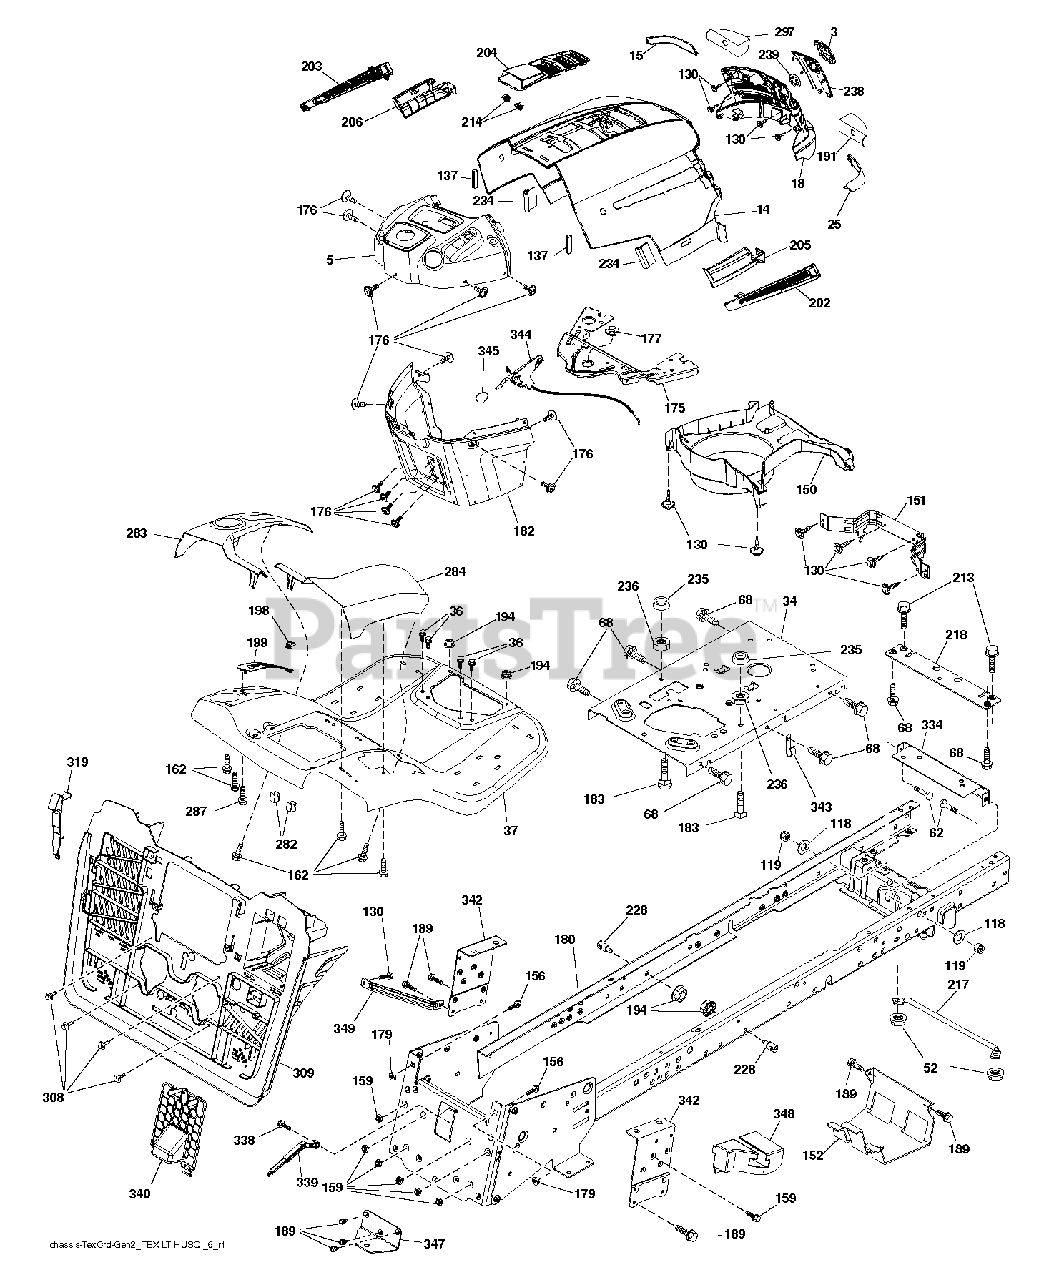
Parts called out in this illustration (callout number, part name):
3	LOGO.HUSQ.GT.LT.CROWN.H
5	SUBASM.DASH.UPPER.HLT.498
14	HOOD.HUSQVARNA.LT.ORANGE
15	LENS.HUSQVARNA LT.RH
18	GRILLE.SVC.HUSQVARNA.GREY
25	LENS.HUSQVARNA LT.RH
34	PLATE.ENGINE.10GA.CRD.GENII
36	SCREW 5/16"
37	FENDER.TEX.SRD.CRD.BASE
52	LOCKNUT
62	BOLT D
68	SCREW LT
118	WASHER
130	SCREW.#10 X 0.750.BOS
137	BUMPER DASH
151	BRACKET PIVOT
152	SHIELD.BROWNING.PNT.GT.V2
159	SCREW, 3/8-16X3/4
162	SCREW.HI-LO.CONSOLE
175	CROSSMEMBER
176	SCREW.#10-24X5/8.RN.QU
177	BUSHING STEERING
182	DASH DASH. LOWER. PREDATOR. LT
183	BOLT.5/16-18X1-1/4 FULL THD
189	SCREW
191	INSERT.REFLECTIVE.RH.
194	NUT LOCK HEX FLANGE 5/16-18
198	INDICATOR.DECK.LIFT.RED
199	PLATE DECK LIFT
202	VENT.SIDE.HUSQVARNA.LT.RT
203	VENT.SIDE.HUSQVARNA.LT.LFT
204	SUBASM.TOP.VENT.HUSQ.LT
205	SKIRT.SIDE.HUSQVARNA.LT.RT
206	SKIRT.SIDE.HUSQVARNA.LT.LEFT
213	BOLT
214	CLIP.RETAINER.TINNER.
217	ROD.PIVOT.HOOD
218	X-PIECE.HOOD.STOP.NON/
228	STUD.FASTNER.W/ANTI-ROTATE
234	BUMPER.HOOD.TEX.HUSQVARNA
235	SPACER FENDER
236	NUT.CENTERLOCK.5/16-
238	TRIM.HUSQ LT.668
282	CLIP.RETAINER.CONSOLE.LT.HUSQ
283	CONSOLE.DECKLIFT.CRDII.498
284	CONSOLE.PEDAL.HYDRO
287	SCREW 1/4X20
297	INSERT REFLECTIVE
308	BOLT, 5/16-18 X 1 3/4
334	BRACKET.ENGINE
338	BOLT BOLT SHOULDER
339	LEVER LEVER BAGGER
342	SUPPORT SUPPORT FENDER
343	CLIP CLIP
344	CONTROL.EZ.MULCH.TEX/CRD
345	RP KNOB.OVAL.TAPERED.3/8-16BLK
347	HITCH TOW
349	BRACKET.SUPPORT.LRVB/CRD
